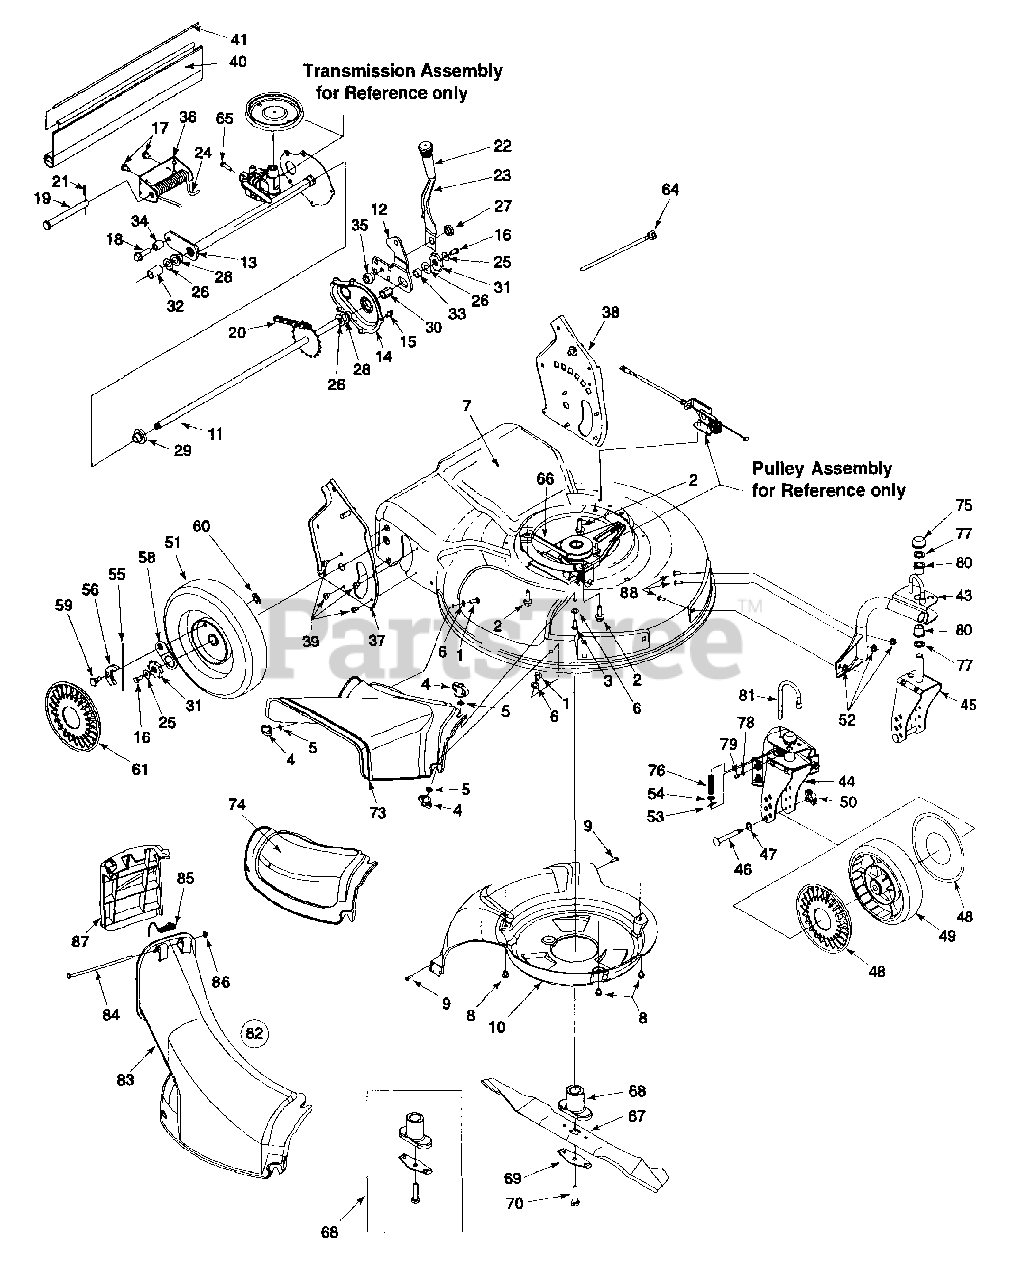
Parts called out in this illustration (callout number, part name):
1	Scr. Carr. 1/4-20 x .62
2	Scr. TT:3/8-18:1.00
3	Carriage Scr. 1/4-20 x .750
4	Wing Nut 1/4-20
5	Nut, Push .25 I.D. x .50 O.D.
6	Wash. Fl. .334 I.D. x .62 x .03
8	Scr. TT. 1/4-20 x .375
9	Scr. HL. 1/2-14 x .750
10	Baffle
11	Rear Axle Assembly
16	Cap Screw HH 1/4-20 x .620
17	Scr. AB 1/4-20 x.625
18	Scr. 3/8 116 x .25
19	Clevis Pin .50 Dia. x 4.82 Lg.
20	Chain-Endls. #48 .500P x 24L
21	Cotter Pin .125 O.D. x .75
23	Spring Lever
24	Torsion Spring
25	Bell Wash. .285 x .75 x .082
26	Fl. Wash. .508 I.D. 1.000 x .020
27	Nut Shld. .825 Dia. x .165 Lg.
28	Hx. Flg. Brg. .506 I.D. x .590 L.
29	Hx. Flg. Brg. .506 I.D. x .715 L.
30	Hx. Slv. Brg. .504 I.D. x .830 L.
31	Wheel Rachet
32	Spa. .550 I.D. x .750 O.D.
33	Spa. .51 .D. x .70 O.D. x 38 L.
34	Spa. .385 x .624 x .700
35	Shld. Spa. .385 I.D. x .715 Lg.
40	Trail Shield
41	Trail Shield Wire
46	Caster Axle .374 Dia x 2.50"
47	Wave Washer
48	Hub Cap w/hole
49	Wheel 7 x 2 Link
50	Wing Nut 1/4-20
51	Wheel 9 x 2 Link
52	Lock Nut 5/15-18
53	Cotter Pin .072 x .12 Lg.
54	Fl. Wash. .330 x .830 x .060
55	Spring, Ratchet, Plastic
56	Pawl - R.H.
58	Ratchet Pawl Plate
59	Scr. Shld. .340 x .285
60	Top Lock Tab Weld Nut 1/4-20
61	Hubcap, w/o hole
64	Cable Tie
65	Hex Scr. 5/16-18
66	Belt, 3/8" x 39.24"
67	21" Mulching Blade
68	Blade Adapter
69	Blade Bell Support
70	Hex Bolt 3/8-24 x 2.5" Lg.
73	Side Discharge Chute
74	Mulch Cover
76	Compression Spring
77	Fl. Wash. .5/8 I.D. x 1" O.D.
78	Fl. Wash. .203 x .403 x .040
79	Fitting - Grease
80	Flange Bearing
81	Locking Pin
82	Chute Ass'y
83	Discharge Chute
84	Pivot Rod
85	Torsion Spring
87	Chute Door
88	Carr. Bolt 5/16-18 x .62
